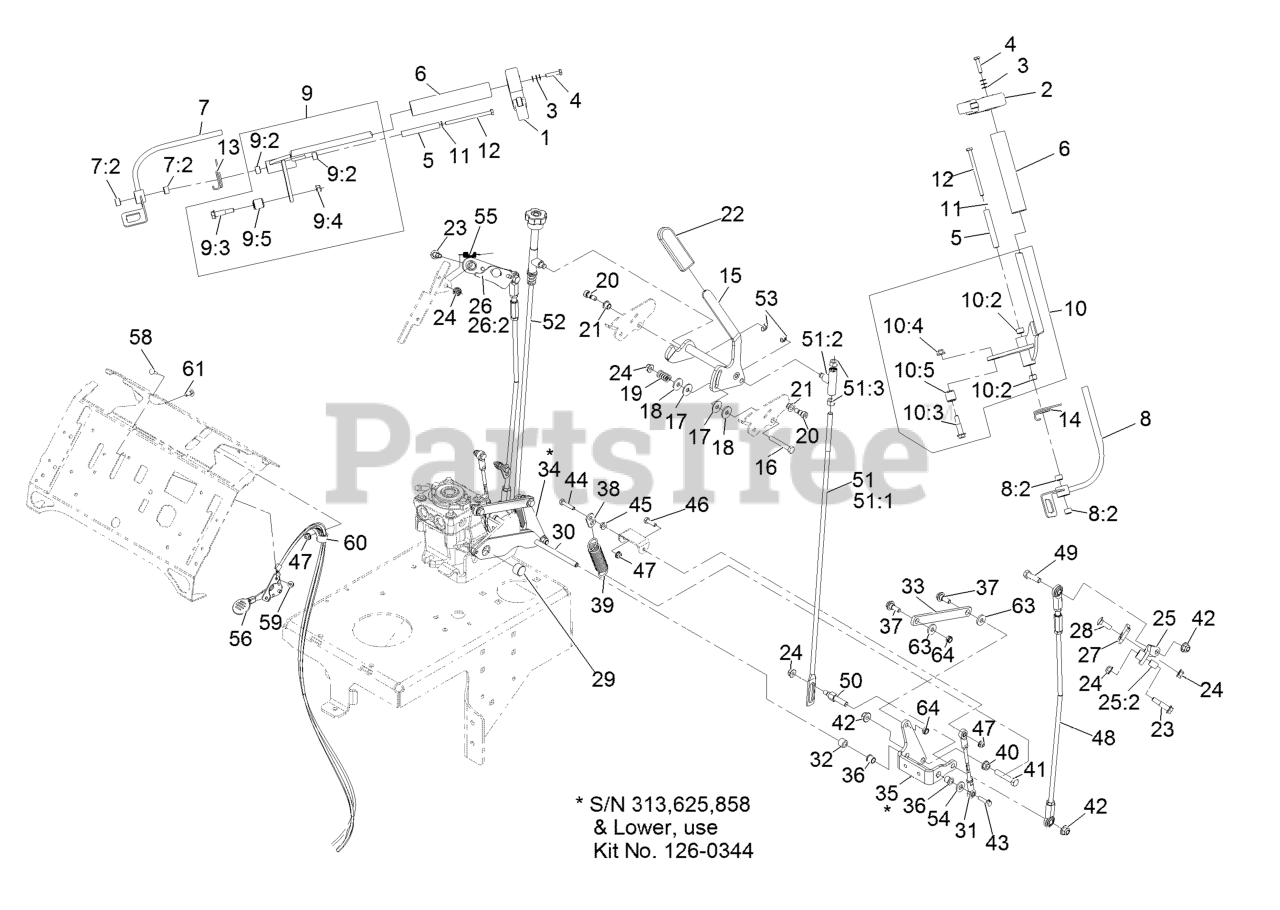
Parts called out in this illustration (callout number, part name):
1	ASM,LATCH RH THUMB
2	ASM,LATCH LH THUMB
3	WASHER-SPRING
4	SCREW-HH
6	GRIP-BAR, HANDLE
7	OPC-W/BUSHING, RH
7:2	BUSHING-SLEEVE
8	OPC-W/BUSHING, LH
8:2	BUSHING-SLEEVE
9	ASM, CONTROL-RH
9:2	BUSHING-SLEEVE
9:3	SCREW-SHOULDER
9:4	NUT-HF, NI
9:5	ASM, ROLLER
10	ASM, CONTROL
10:2	BUSHING-SLEEVE
10:3	SCREW-SHOULDER
10:4	NUT-HF, NI
10:5	ASM, ROLLER
11	SCREW-HH
12	SCREW-HH
13	SPRING, TORSION
14	SPRING, TORSION
15	SPEED CONTROL ASM
16	SCREW-HH
17	WASHER-FRICTION
18	WASHER-FRICTION
19	SPRING-COMPRESSION
20	SCREW-HSH
21	BUSHING
22	GRIP-HANDLE, STEERING
23	SCREW-SHOULDER
24	NUT-HF, NI
25	ARM ASM-LEFT
25:2	SLEEVE-BEARING
26	ARM ASM -RIGHT
26:2	SLEEVE-BEARING
28	BOLT-CARR
29	PIN-BELLCRANK LINK RETAIN
30	BELLCRANK LINK ASM
31	ASM, LINK
32	SPACER-WHEEL
33	LINK-BELLCRANK, PUMP
34	BELLCRANK-LOWER, RT
35	BELLCRANK-LOWER, LT
36	BEARING
37	SCREW-SHOULDER
38	ANCHOR, SPRING
39	SPRING-EXTENSION
40	NUT-HHF, WHIZ
41	SCREW-HH
42	NUT-HF, NI
43	SCREW-HHF
44	SCREW-HH
46	SCREW-HH
48	ASM, ROD
49	SCREW-HH
50	STUD-CONTROL, SPEED
51	ASM, ROD LEFT
51:1	ROD, LEFT
51:3	NUT-HEX
52	ASM, ROD RIGHT
53	RING-RETAINING
54	WASHER-FRICTION
55	SPRING-EXTENSION
56	CONTROL-THROTTLE
58	BOLT-CARR
59	NUT-LOCK, FLANGE
60	CLAMP-CABLE
61	SCREW-CARR
63	WASHER-FLAT
64	NUT-LOCK, NI
